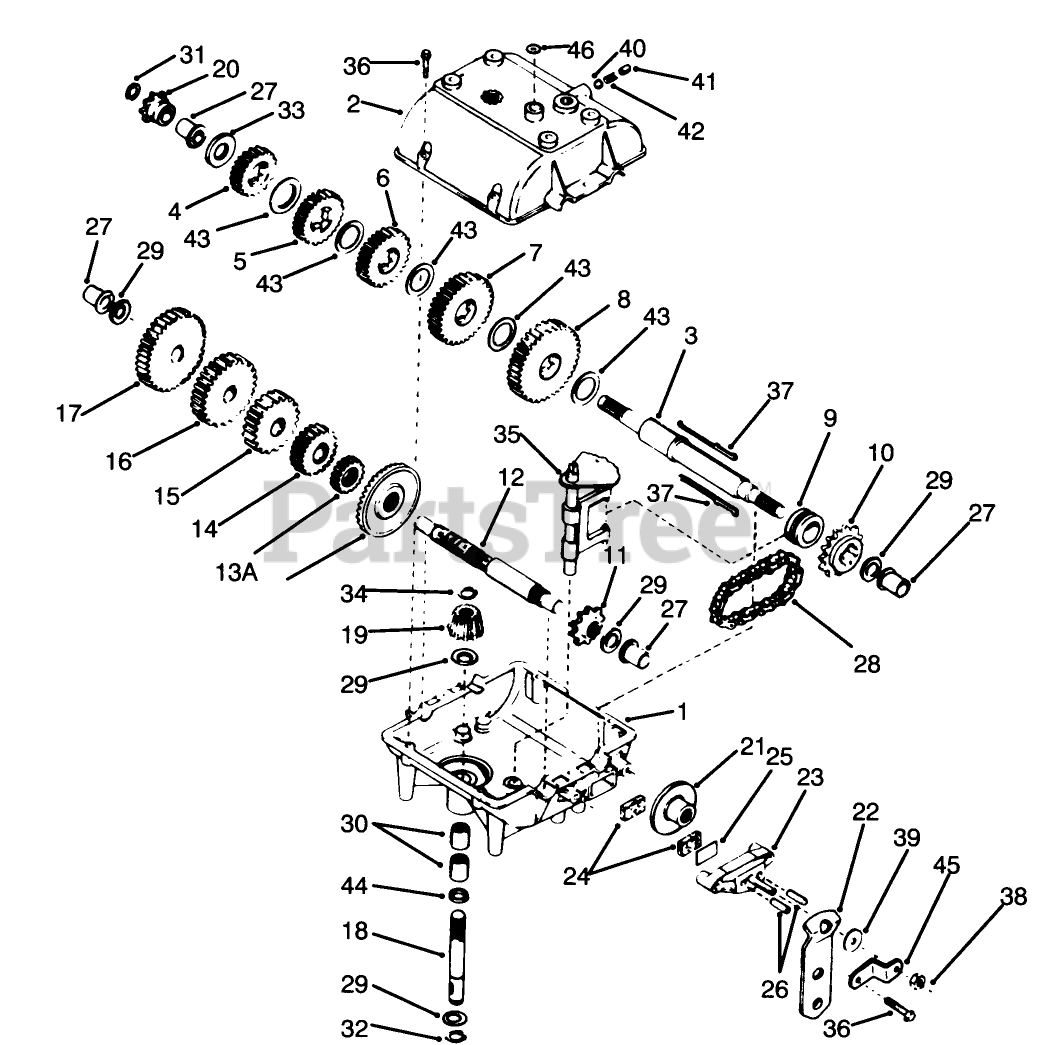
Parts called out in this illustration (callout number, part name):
1	Case-Transmission
2	Cover-Transmission
3	Shaft-Output
4	Gear-Spur 20 teeth
5	Gear-Spur (22 teeth)
6	Gear-Spur, 25 Teeth
7	Gear-Spur, 30 Teeth
8	Gear-Spur, 35 Teeth
9	Collar-Shift
10	Sprocket-18 Teeth
11	Sprocket-9 Teeth
12	Countershaft
13	Gear-Bevel (42 Teeth)
13A	Gear-Spur 15 Teeth
14	Gear-Spur, 20 Teeth
15	Gear-Spur, 25 Teeth
16	Gear-Spur (28 teeth)
17	Gear-Spur (30 teeth)
18	Shaft-Input
19	Bevel Pinion-Input
20	Sprocket (8Teeth)
22	Lever-Brake
23	Nozzle-Carburetor
24	Brake Pad
25	Brake Pad Plate
26	Dowel Pin
27	Bushing-Flange
28	Chain-Roller #41
29	Washer
30	Bearing-Needle
31	Piston Asm (.020 O S)
32	Ring-Snap
33	Washer
34	Ring-Retainer
35	Rod and Fork ASM
36	Ring Set (.020 O S)
38	Locknut
39	Washer
40	Ball-Steel
41	Screw-Set
42	Spring
43	Washer
44	O Ring
45	Bracket
46	Cut Seal-Square
